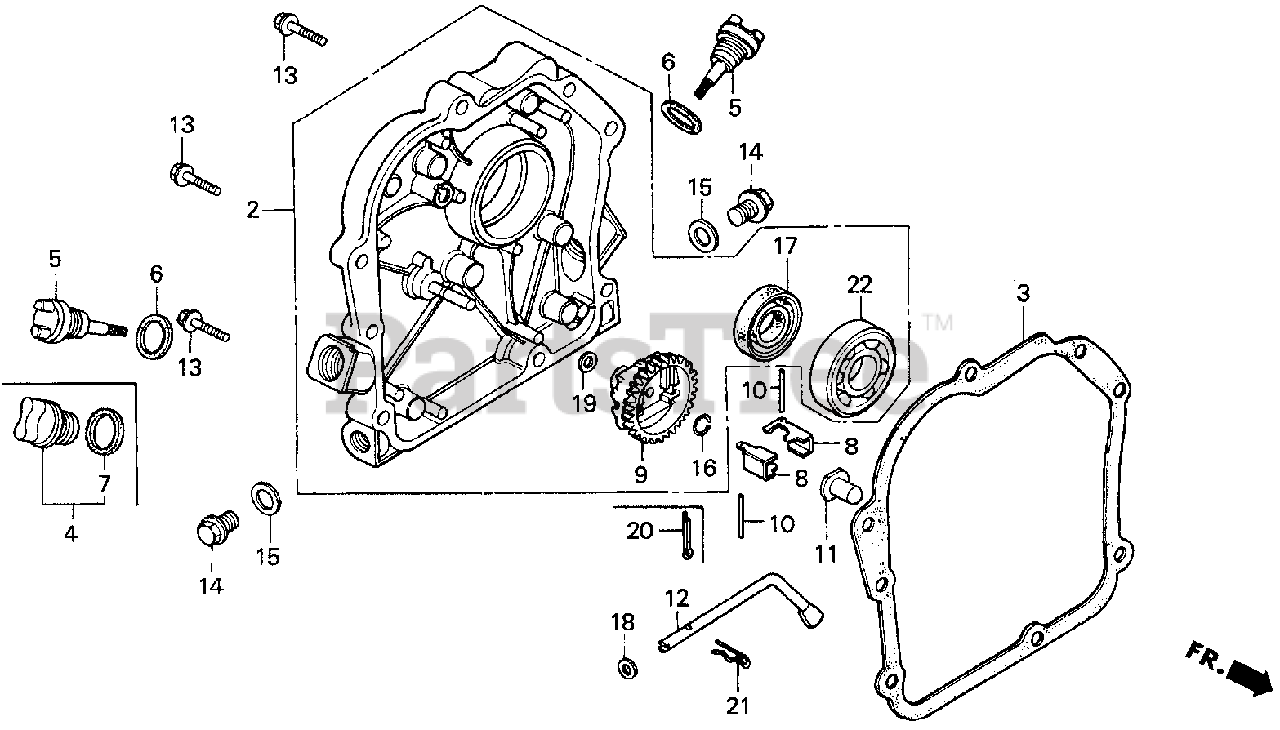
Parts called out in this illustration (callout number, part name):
2	COVER ASSY., CRANKCASE
3	GASKET, CASE COVER
5	CAP, OIL FILLER
6	GASKET, OIL FILLER CAP
8	WEIGHT, GOVERNOR
9	HOLDER, GOVERNOR WEIGHT
10	PIN, GOVERNOR WEIGHT
11	SLIDER, GOVERNOR
12	SHAFT, GOVERNOR ARM
13	BOLT, FLANGE (6X28)
14	BOLT, DRAIN PLUG
15	WASHER, DRAIN PLUG (12MM)
16	CLIP, GOVERNOR HOLDER
17	OIL SEAL (17X30X6) (NOK)
18	WASHER, PLAIN (5MM)
19	WASHER, PLAIN (6MM)
20	PIN, COTTER (2.5X28)
21	PIN, LOCK (8MM)
22	BEARING, RADIAL BALL (6203)
